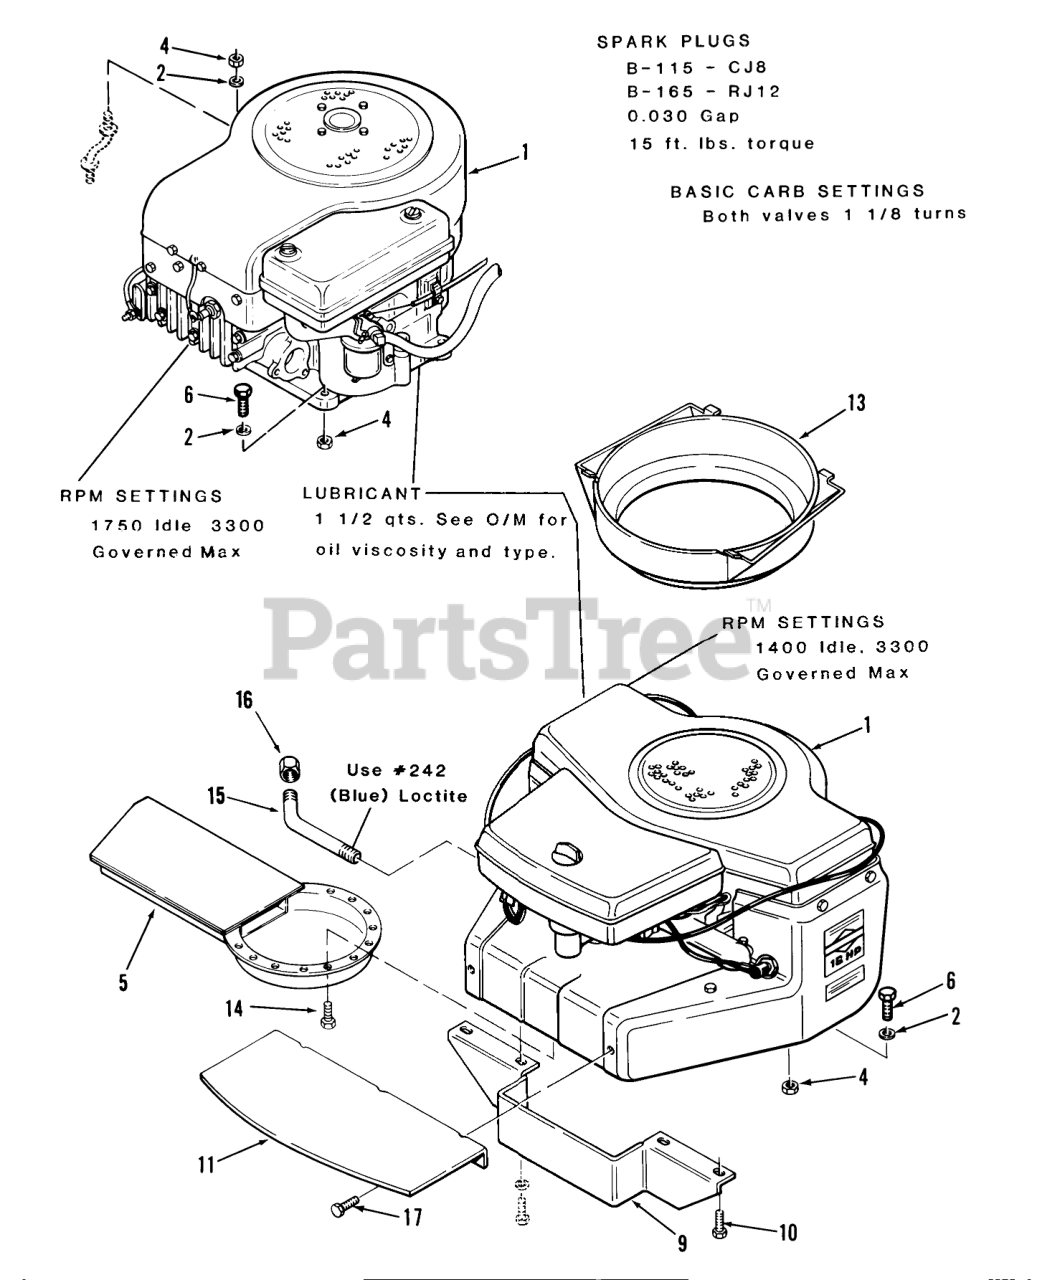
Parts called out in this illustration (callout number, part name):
1	Engine-16HP-B&S Model 402707, Type 0130-05 216-5 Only
1	Engine-11HP-B&S Model 253707, Type 0131-01-B-115 Only
2	WASHER 5/16 SAE
4	Nut
5	Exhaust Deflector B-165 Only
6	Bolt
6	HHCS
9	Duct-Rear 216-5 Only
10	Bolt
11	Duct-Front B-165 Only
13	DUCT-AIR INTAKE
14	SCREW 8-32X3/8
16	Cap
17	Screw-Hex HD Slotted
